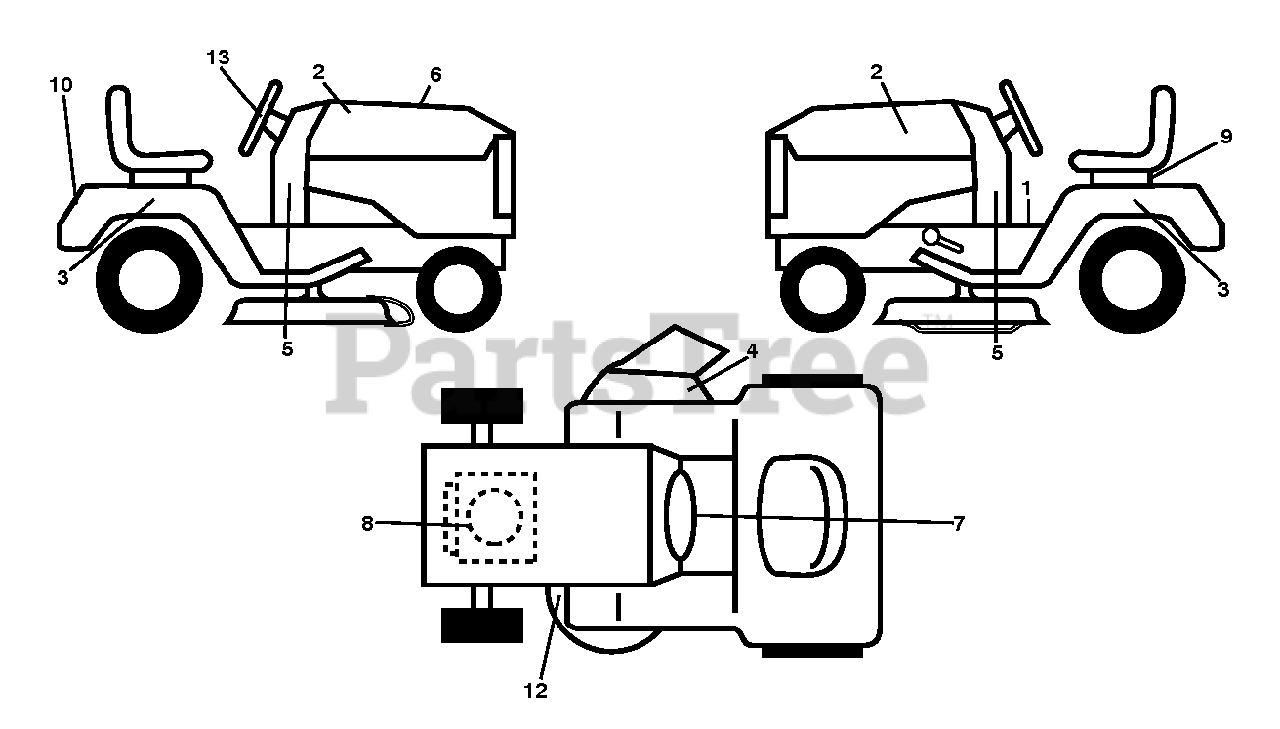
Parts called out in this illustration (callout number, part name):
1	DECAL.WARNING.2007.ENG/FR
2	DECAL.HOOD.ALPHA.RH/LHSET.2014
3	DECAL FENDER
4	DECAL.MOWER.WARN.KEEP.HAND.AWY
7	DCL.WARNING.SPARK.IGNITION.CA
8	DECAL.ENG.BS.15_5HP.DOM.381681
9	DECAL BTRY SYMBOLS
10	DECAL.FNDR.LOGO.2014.POULAN
12	DECAL.V-BELT.SCH.42/46"MEC/ELE
